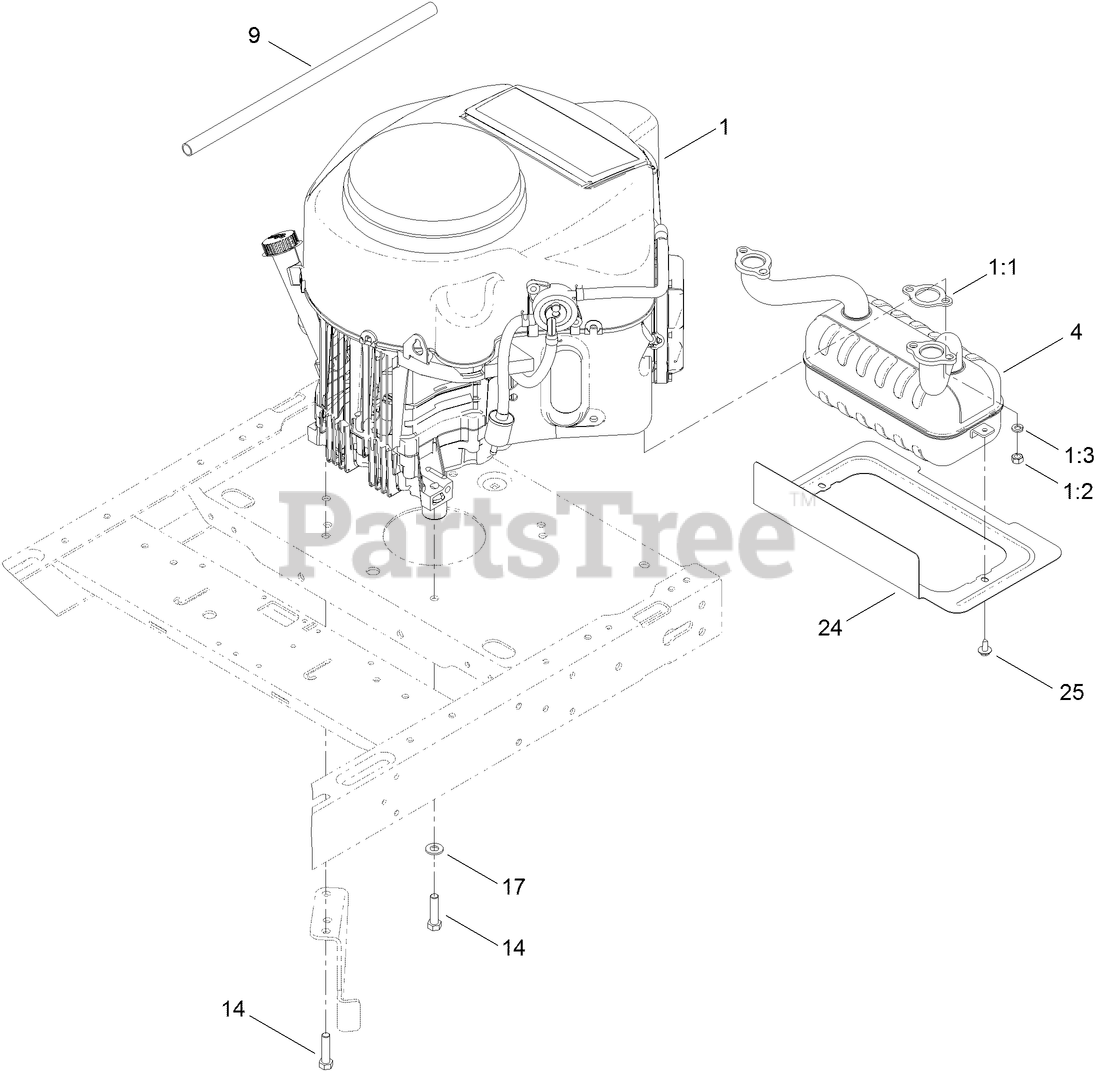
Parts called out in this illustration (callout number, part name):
1:1	GASKET-EXHAUST
1:3	WASHER-LOCK
4	MUFFLER-KAWASAKI
9	TUBE-DRAIN, OIL
14	BOLT-HH
17	WASHER-FLAT
24	SHIELD-HEAT
25	SCREW-HHFTF
